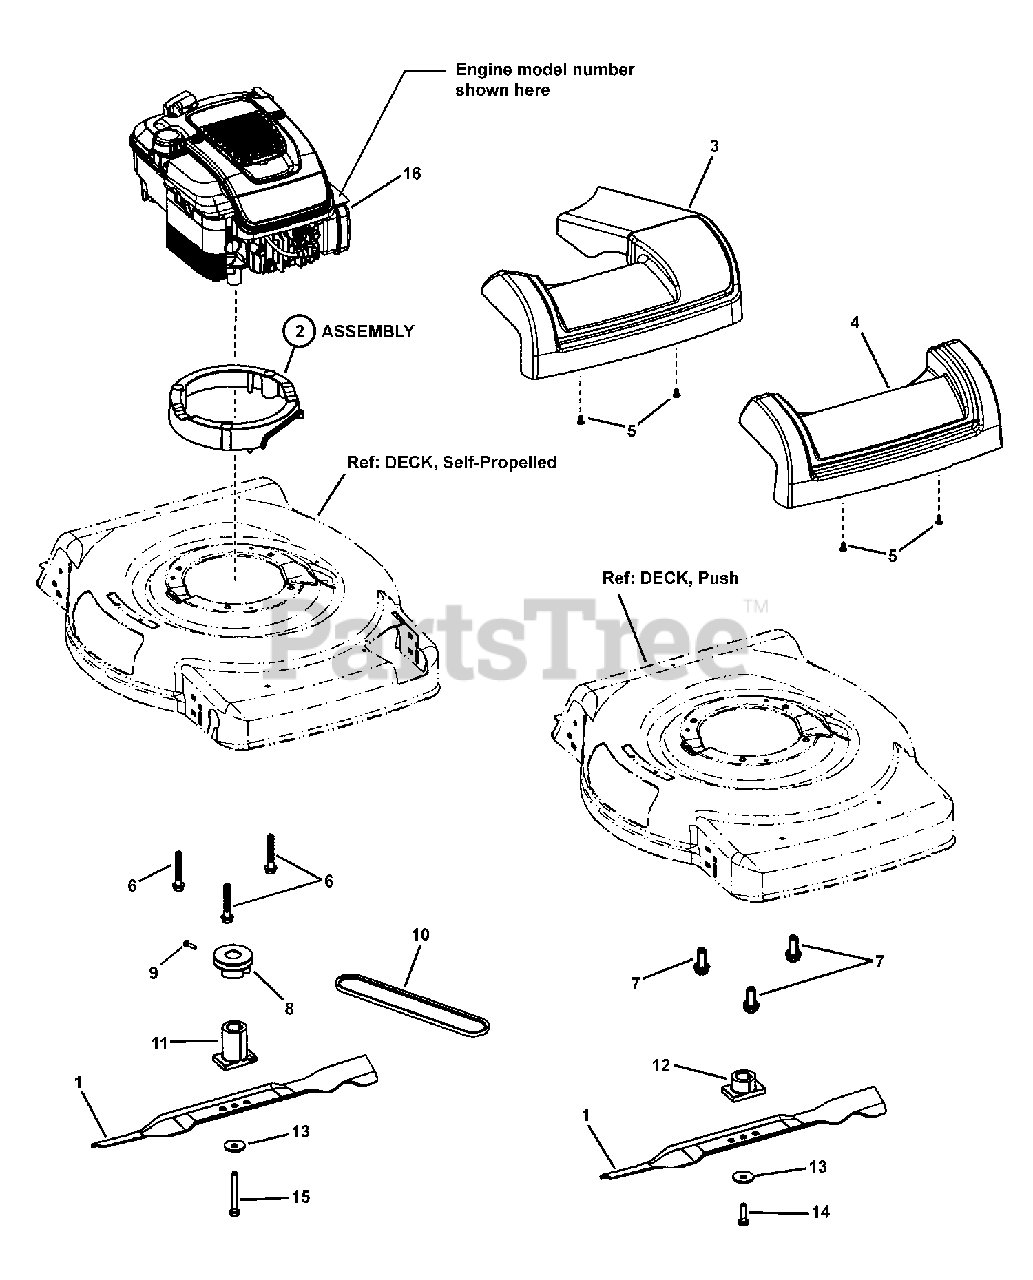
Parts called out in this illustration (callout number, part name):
1	BLADE, 22", Walk Mower
2	ASSEMBLY, Engine Spacer, 22" WBM, Self-Propelled
3	FRONT DECK COVER, 22" Front Wheel Drive
4	FRONT DECK COVER, Rear Discharge WBM
5	SCREW, 4.8 x 1.59 x 13mm, Round Washer Head Hi-Lo (Torx)
6	BOLT, 3/8-16 NS x 2-1/2"
7	SCREW, 3/8-16 x 1" Hex Washer Self-Tap
8	PULLEY, Engine, 22" Deck, Single Speed
9	SCREW, #8-11 x 5/8" Poly
10	** BELT, Drive (3L Section, 33.75" effective length)
11	BLADE HUB, 22" Deck, Self Propelled
12	BLADE HUB, 22" Deck, Push
13	WASHER, .38" I.D. x 1.183 O.D. Bellville
14	SCREW, 3/8-24 x 1-1/4" Hex Head Cap, GR 5
15	BOLT, 3/8-24 x 3-1/4" Hex Head, GR 8
16	* ENGINE, B&S, 650 Series X-Spec
16	* ENGINE, B&S, 675 Series X-Spec
